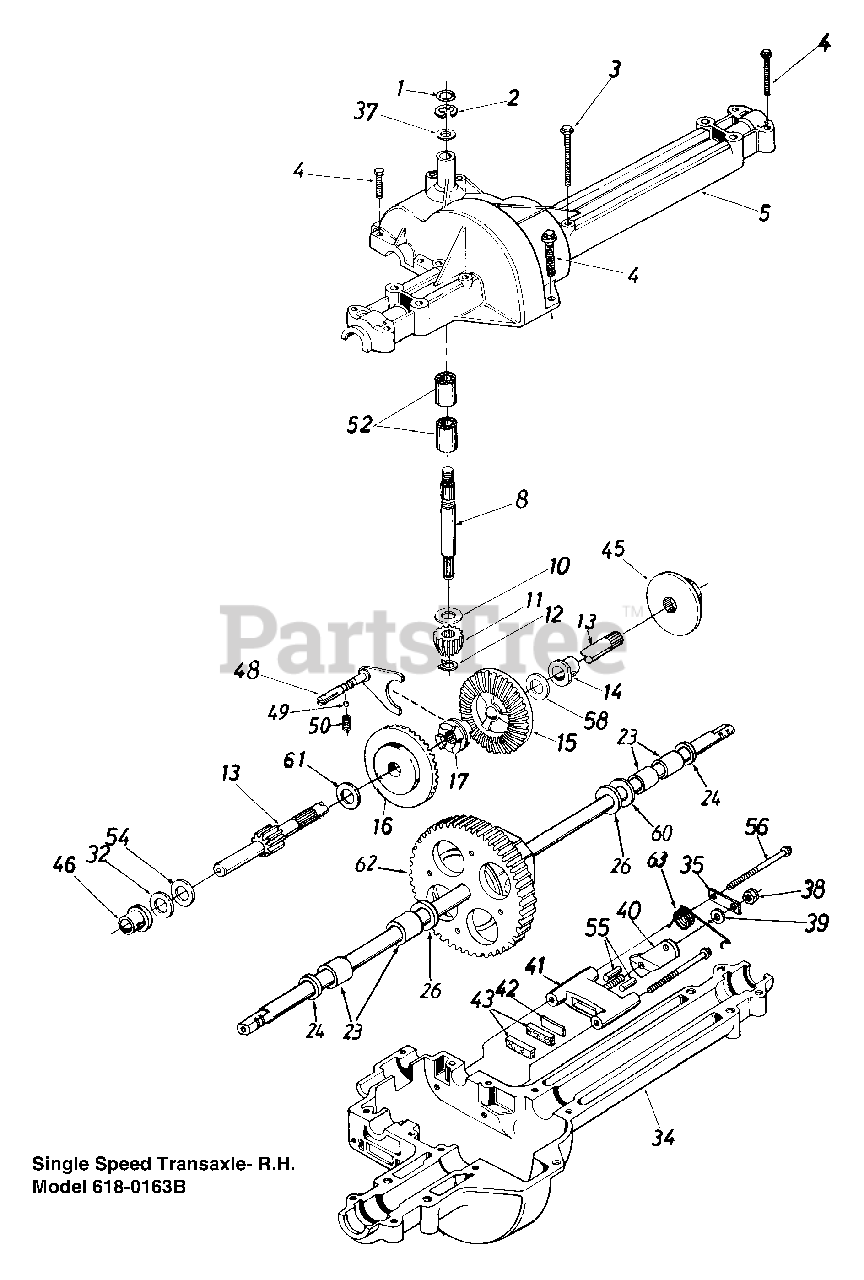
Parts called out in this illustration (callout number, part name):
3	Hex Wash. TT-Tap Scr. 1/4-20 x 1.75"
4	Hex Tap Scr. 1/4-20 x 1.25" Lg.
5	Upper Housing
10	Thrust Washer 5/8" I.D. x1.25" O.D.
11	Pinion Input 14T
12	Retaining Ring
13	Drive Shaft-R.H. Brake
14	Flange Brg. 5/8" I.D. x 3/4" Lg.
15	Bevel Gear 42T Small I.D.
16	Bevel Gear 42T Large I.D.
17	Clutch Collar
23	Sleeve Bearing 3/4" I.D. x1.0" Lg.
24	Oil Seal 3/4" I.D.
26	Fl-Wash. .760" I.D. x 1.5" O.D.
32	Thrust Wash. 5/8" I.D. x 1" O.D. x .025"
32	Fl-Wash. 5/8" I.D. x 1" O.D. x .030" Thk.
32	Thrust Wash. 5/8" I.D. x 1" O.D. x .035"
32	Fl-Wash. 5/8" I.D. x 1" O.D. x .040" Thk.
34	Lower Housing
35	Anti-Rotation Brkt.
37	Fl-Wash. 5/8" I.D. x 1" O.D. x .020" Thk.
37	Fl-Wash. 5/8" I.D. x 1" O.D. x .030" Thk.
37	Fl-Wash. 5/8" I.D. x 1" O.D. x .040" Thk.
38	Hex Nut 5/16-24 Thd.
39	Fl-Wash. .344" I.D. x .875" O.D.
40	Actuating Arm
41	Brake Yoke
42	Puck Plate
43	Brake Puck
46	Flange Bearing 5/8" I.D. x 15/16" Lg.
48	Shift Fork Ass'y.
49	Ball Detent .250" Dia.
50	Spring Detent
52	Needle Brg. 5/8" I.D. x 1/2" Lg.
54	Fl-Wash. 5/8" I.D. x 1" O.D.x .020 Thk.
55	Actuating Pin 5/16" Dia.
56	Hex Wash Hd. Self-Tap Scr.1/4-20 Thd.
58	Fl-Wash. 5/8" I.D. x 1" O.D. x.020 Thk.
60	Fl-Wash. .76" I.D. x 1.5" O.D. x .010" Thk.
60	Fl-Wash. .76" I.D. x 1.5" O.D. x .020" Thk.
60	Fl-Wash. .76" I.D. x 1.5" O.D. x .030" Thk.
60	Fl-Wash. .76" I.D. x 1.5" O.D. x .060" Thk.
61	Thrust Washer
62	Differential Ass'y.
63	R.H.-Brake Spring
